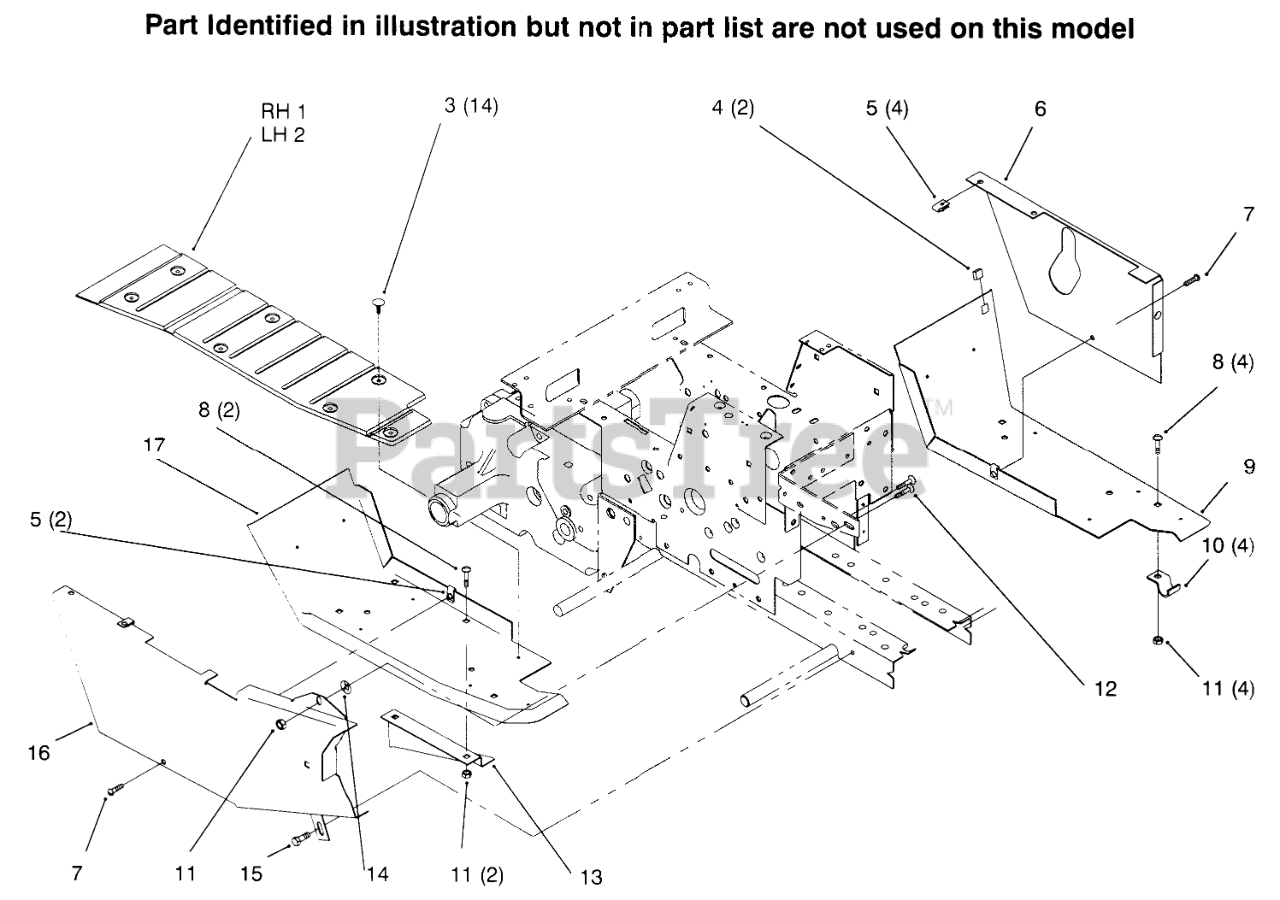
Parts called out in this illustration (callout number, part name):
1	PAD-FOOT RH
2	PAD-FOOT LH
3	Fastener-Panel
4	BUMPER
6	Cover-Side LH
7	SCREW-PPH
8	BOLT-CARR
9	Footrest LH
10	BRACKET
11	NUT-LOCK, NI
12	BOLT-CARR
13	GUID-LOWER BLTR
14	NUT-PUSH
15	Bolt
16	Belt Guard
17	Footrest RH
